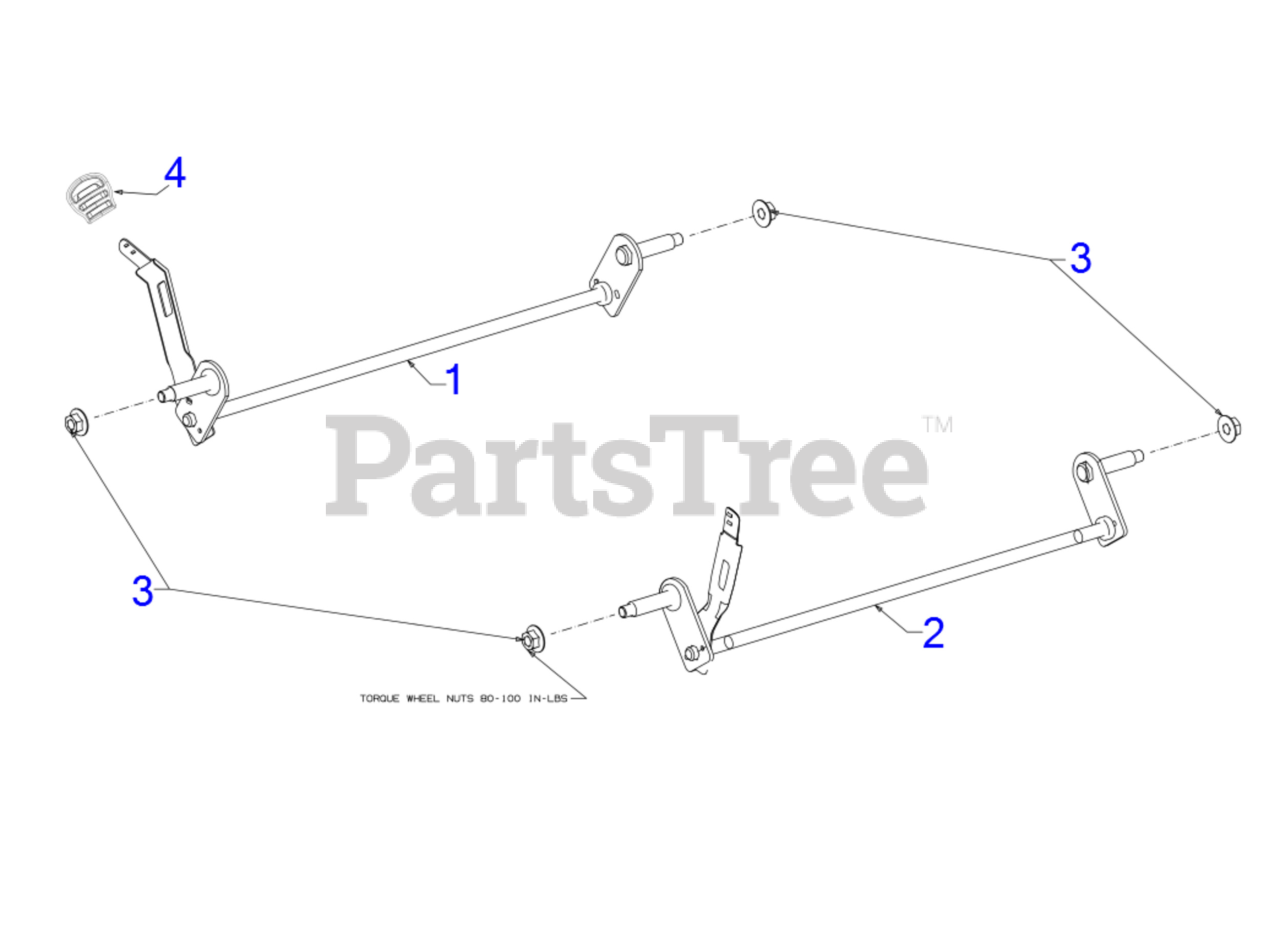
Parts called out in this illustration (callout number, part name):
1	8" REAR AXLE ASSEMBLY
2	7" FRONT AXLE ASSEMBLY
3	FLANGE LOCK NUT
4	HEIGHT ADJUSTMENT KNOB
